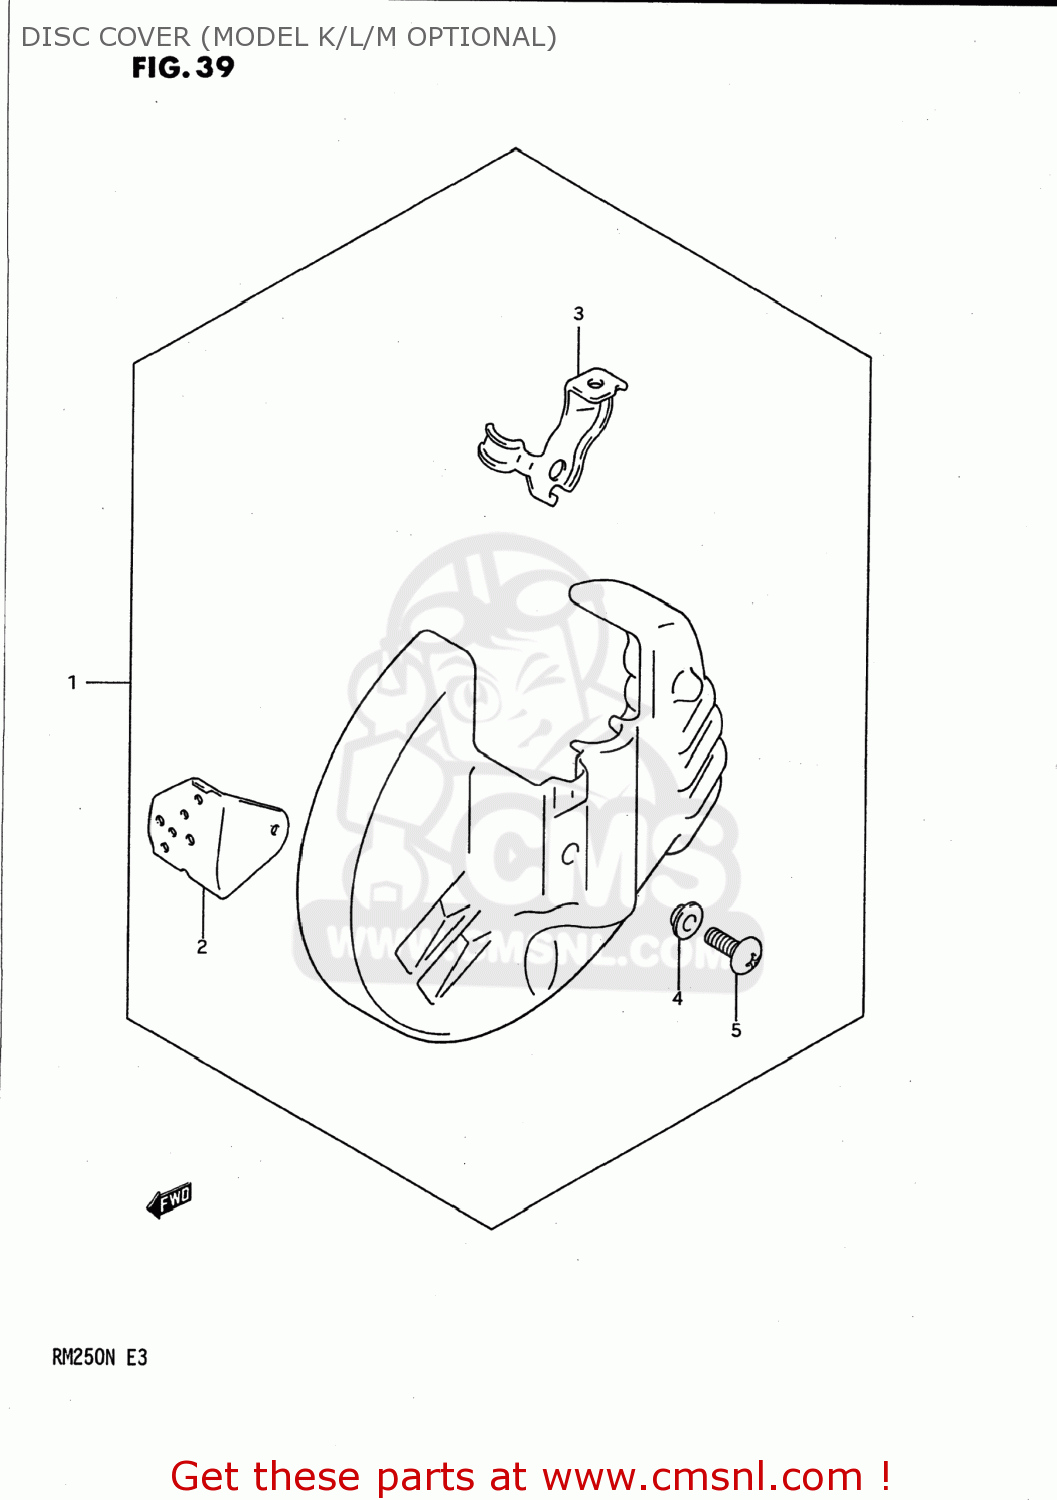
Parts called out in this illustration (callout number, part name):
1	COVER SET,FRONT DISC
2	CLAMP,FRONT BRAKE HOSE
3	CLAMP,FRONT BRAKE HOSE
4	WASHER
5	SCREW 6X12
